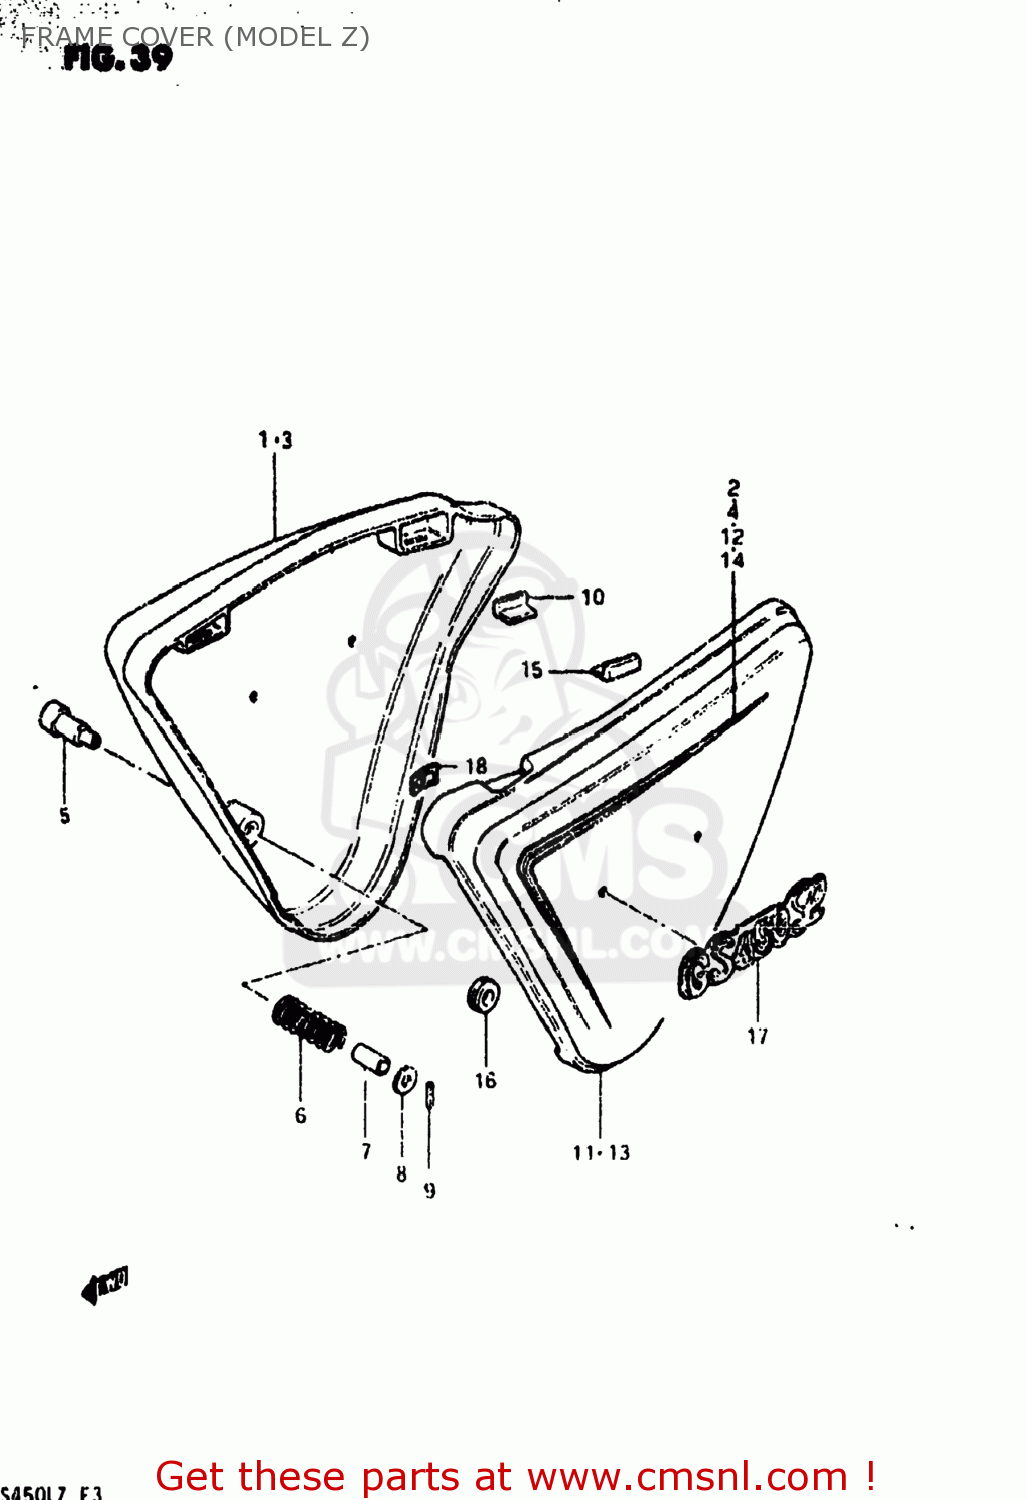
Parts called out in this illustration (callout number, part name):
1	COVER,FRAME,RIGHT
2	TAPE SET,FRAME COVER
3	COVER,FRAME,RIGHT
4	TAPE SET,FRAME COVER,RIGHT
5	KNOB, FRAME COVER RH
6	SPRING
7	SPACER(14.9X17.3X13.5)
8	WASHER (6.5X24X1.6)
9	PIN,SPRING(2.5X18)
10	CUSHION,FRAME COVER
11	COVER,FRAME,LEFT
12	TAPE SET,FRAME COVER,LEFT
13	COVER,FRAME,LEFT
14	TAPE SET,FRAME COVER,LEFT
15	CUSHION,FRAME COVER
16	CUSHION
17	EMBLEM,FRAME COVER
18	NUT
